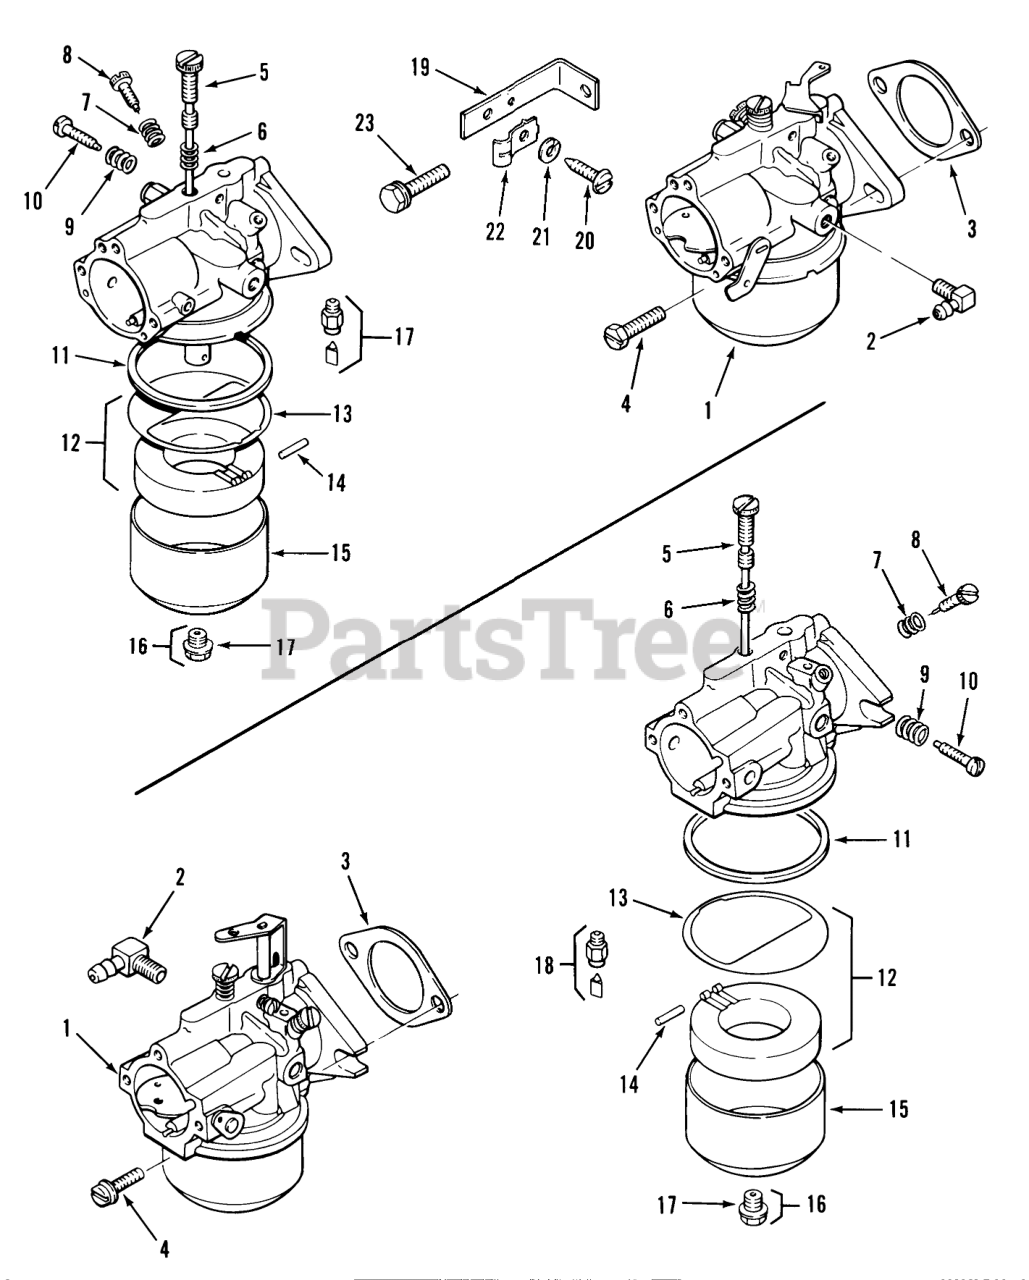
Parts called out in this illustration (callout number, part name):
1	Carb. Assy (includes 5 thru 8) 308 Only
2	Connector 90
3	Gasket-Flange
4	Sltd. Hex Hd. Screw 1/4-20 x 1/4 308 Only
5	Main Fuel Adj. Needle 308 Only
6	Main Fuel Spring
7	Idle Fuel Spring
8	Idle Fuel Adj. Needle 308 Only
9	Idle Speed Spring
10	Screw
11	Bowl Gasket
12	Float Kit (includes item 13)
13	Bowl Baffle Gasket
14	Float Hinge Pin
15	Fuel Bowl 308 Only
16	Fuel Bowl Retainer Screw (includes item 17) 308 Only
17	Bowl Retainer Screw Gasket
19	Choke Bracket 308 Only
20	Sltd. Pan Hd. Screw 10-24 x 3/8 308
21	Lockwasher #10
22	Cable Clip
23	H.C. Sems Screw 1/4-20 x 3/4
